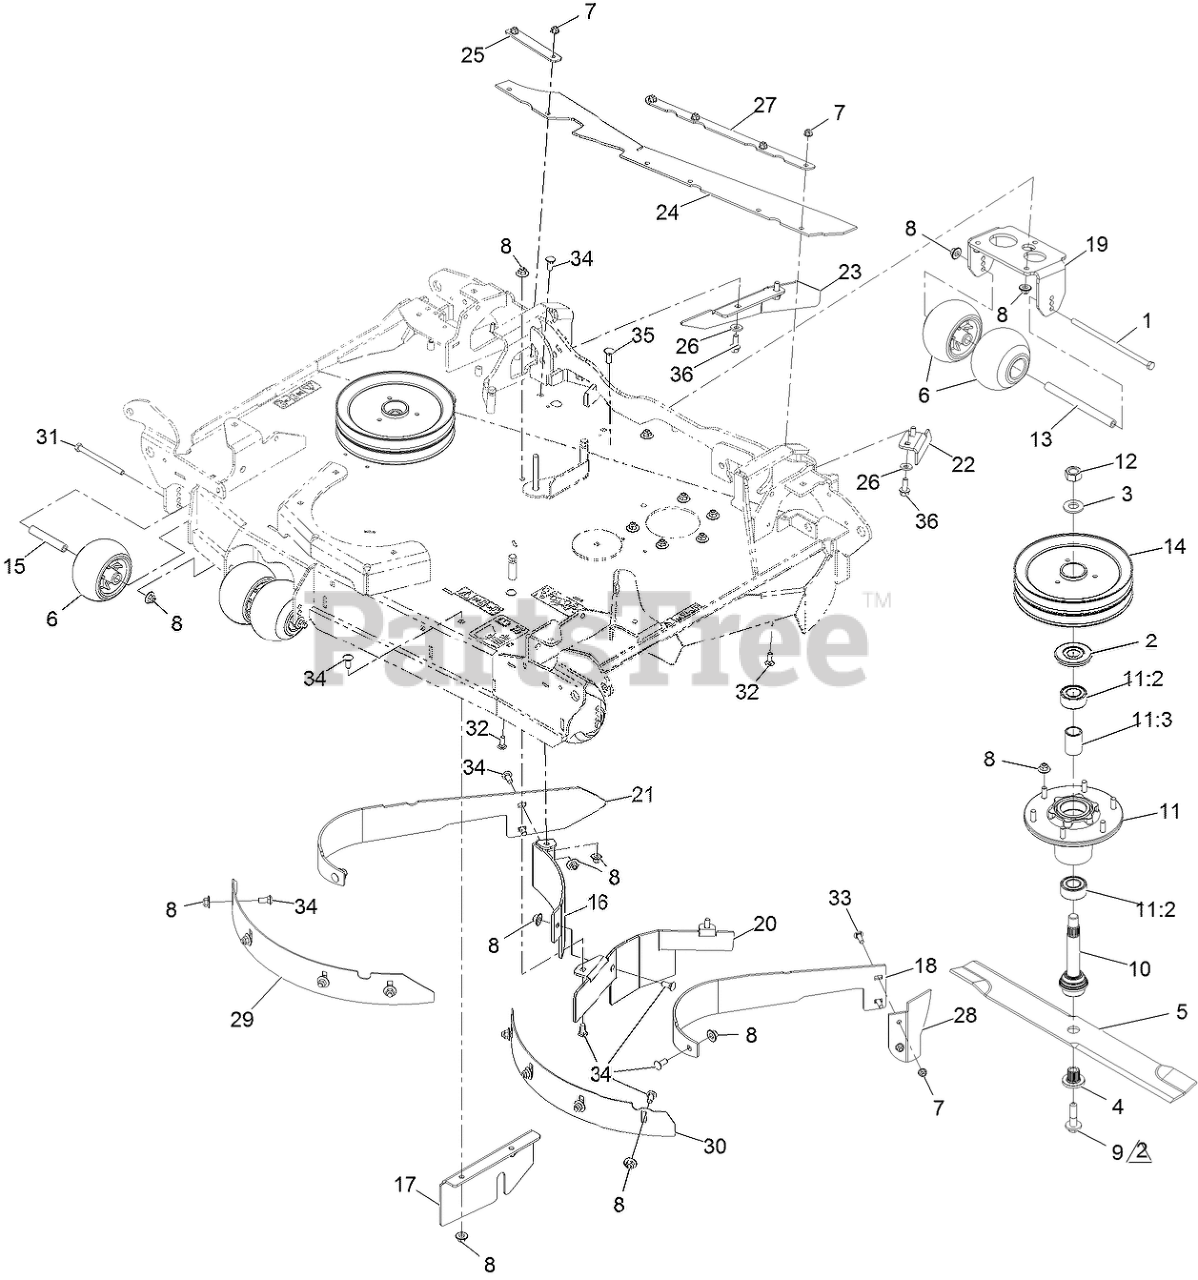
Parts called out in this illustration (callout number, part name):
1	SCREW-HH
2	GUARD-BEARING, TOP
4	BUSHING,SPLINED
6	ROLLER-SCALP, ANTI
7	NUT-HF, NI
8	Nut-Nyloc 3/8-16 Flg
9	SCREW,SEMS 1/2-20 X 2.19
10	ASM-SPINDLE AND SEAL
11	ASM-CUTTER HSG
11:2	BEARING-3205 TRASHGUARD
11:3	SPACER-BEARING
12	NUT-HEX
13	SPACER-WHEEL
14	SHEAVE-DOUBLE 96RD
15	SPACER-WHEEL SHORT
16	BAFFLE-CENTER, REAR (RH)
17	PLATE-BLOCK, FRONT
18	BAFFLE-DOGLEG, CENTER (LH
19	BRACKET-ANTISCALP, REAR
20	BAFFLE-CENTER
21	BAFFLE-DOGLEG, CENTER (RH
22	BAFFLE-BREAKER
23	PLATE-FIN, DISCHARGE
24	FLAP-DISCHARGE
25	SUPPORT-FLAP, LH
26	WASHER-BELLEVILLE
27	SUPPORT-FLAP, LH
28	GUARD-DISCHARGE
29	BAFFLE-DEPTH, LH
30	BAFFLE-DEPTH, RH
31	SCREW-HH
32	SCREW-CARR
33	SCREW-CARR
34	BOLT-CARR
35	BOLT-CARR
36	SCREW-HHF
